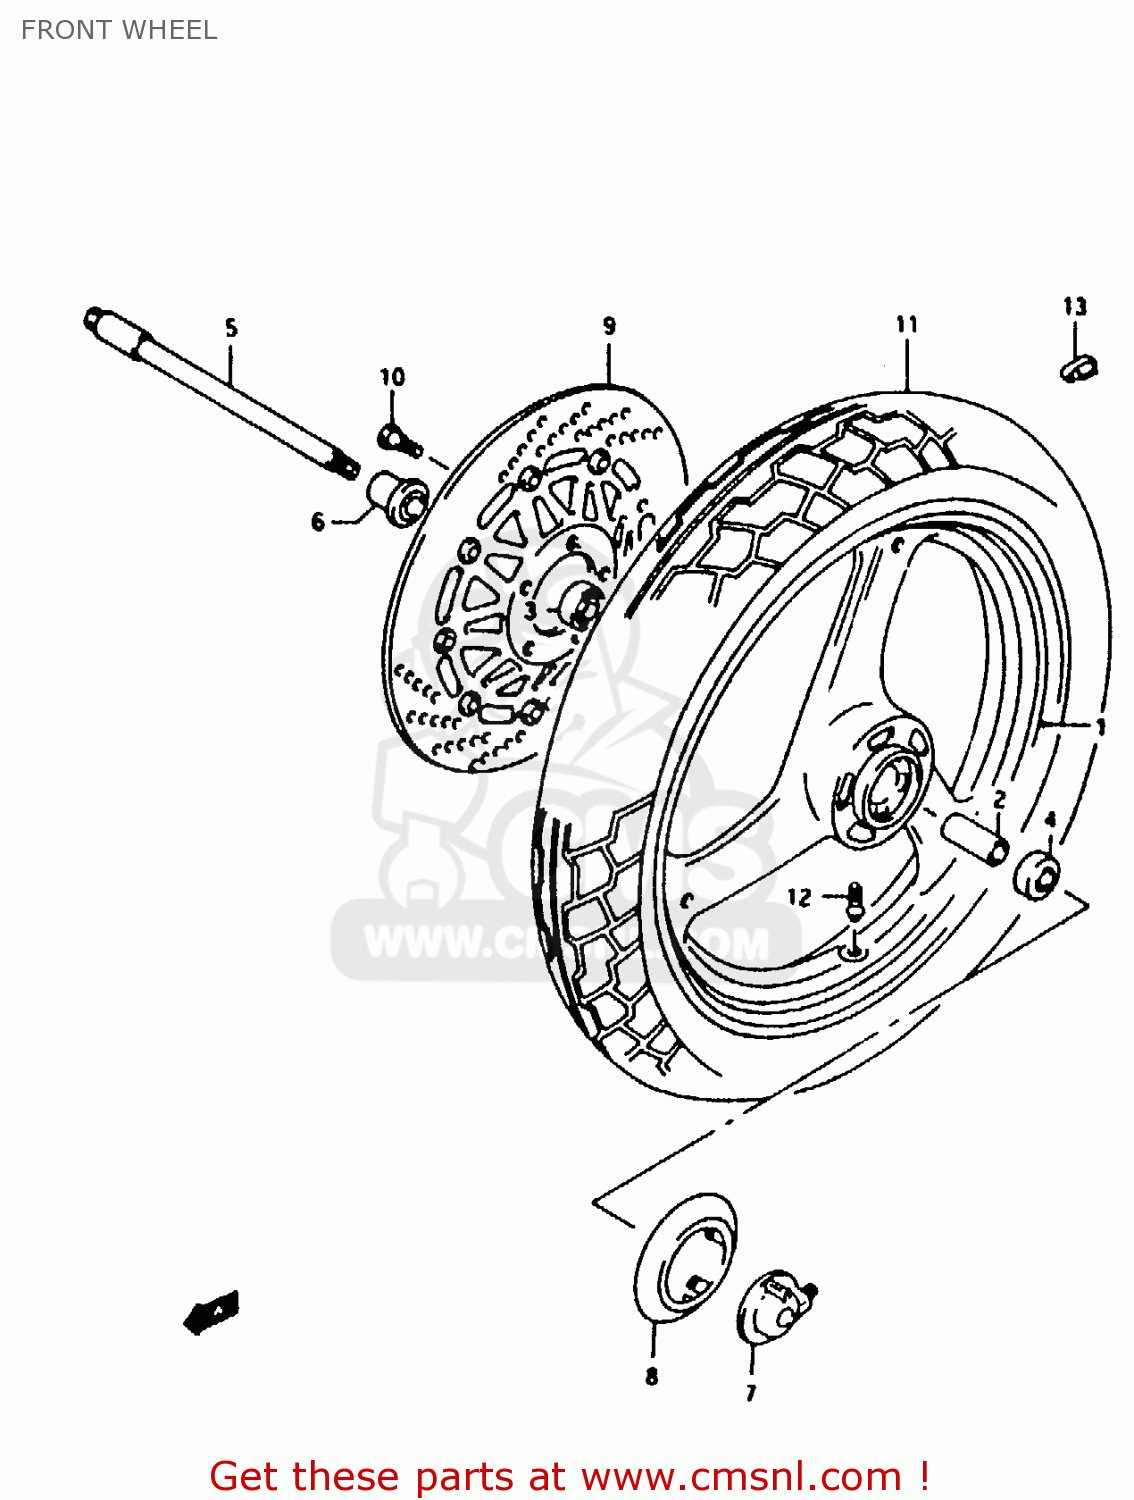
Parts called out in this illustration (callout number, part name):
1	WHEEL, FRONT (MT2.50*17) (GRAY)
2	SPACER (15.3*21.7*72)
3	BEARING
4	BEARING
5	AXLE,FR
6	SPACER, FRONT AXLE RH
7	BOX ASSY,SPEEDOMETER GEAR
8	COVER,FR HUB,R
9	DISC,FR BRAKE,R
10	BOLT 8X33
11	TIRE, FRONT (100/80-17 52S) (DUNLOP)
12	VALVE ASSEMBLY,WHEEL,TR412
13	BALANCER,WHEEL
